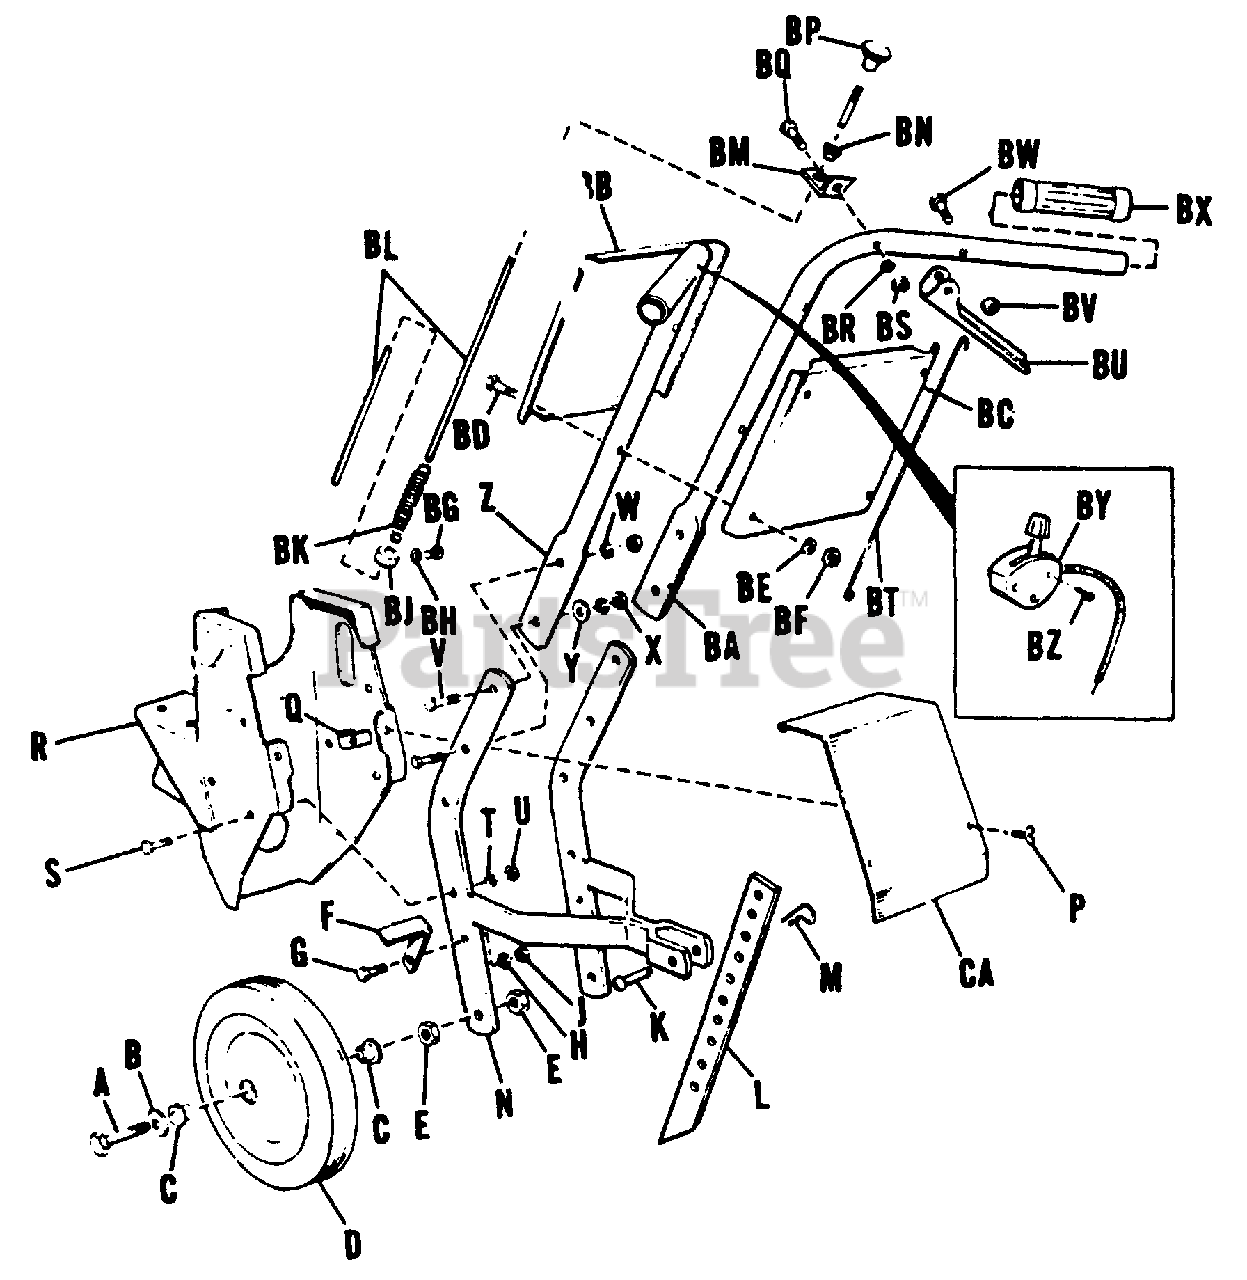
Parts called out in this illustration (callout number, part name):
A	Capscrew, Hex Hd., 1/2-13 x 3-1/4"
B	Washer, Plain, 1/2"
C	Wheel Bushing
D	Wheel & Tire Assembly
E	Hex Jam Nut, 1/2"-13
G	Capscrew, Hex Hd., 3/8-16 x 1"
H	Lock Washer, 3/8"
J	Hex Nut, Full, 3/8"-16
K	Pin
L	Depth Bar
M	Spring Clip
N	Frame Assembly
P	Thumbscrew
Q	Speed Nut
R	Body Assembly
S	Capscrew, Hex Hd, 3/8-16 x 1"
T	Lock Washer, 3/8"
U	Hex Nut, Full, 3/8-16
V	Caspscrew, Hex Hd, 3/8-16 x 1"
W	Lock Washer, 3/8"
X	Hex Nut, Full, 3/8-16
Y	Washer, Plain, 3/8"
Z	Handle, Left Hand
BA	Handle, Right Hand
BB	Handle Cover
BC	Handle Cover
BD	Capscrew, Hex Hd, 1/4-20 x 1-1/2"
BE	Lock Washer, 1/4"
BF	Hex Nut, Full, 1/4"-20
BG	Set Screw, Sq. Hd., 1/4-20 x 3/8"
BH	Washer, Plain 3/16"
BJ	Set Collar
BL	Reverse Rod
BM	Bracket, Bushing
BP	Reverse Knob
BQ	Capscrew, Hex Hd, 1/4-20 x 1-1/2"
BR	Lock Washer, 1/4"
BS	Hex Nut, Full, 1/4-20
BT	Extension, Spring
BU	Clutch Grip
BV	Hex Nut, Lock, 1/4-20
BW	Capscrew, Hex Hd, 1/4-20 x 1-1/2"
BX	Handle Grip
BY	Throttle Control Assembly
BZ	Screw,Self Tapping, #10-24 x 1"
CA	Body Cover
